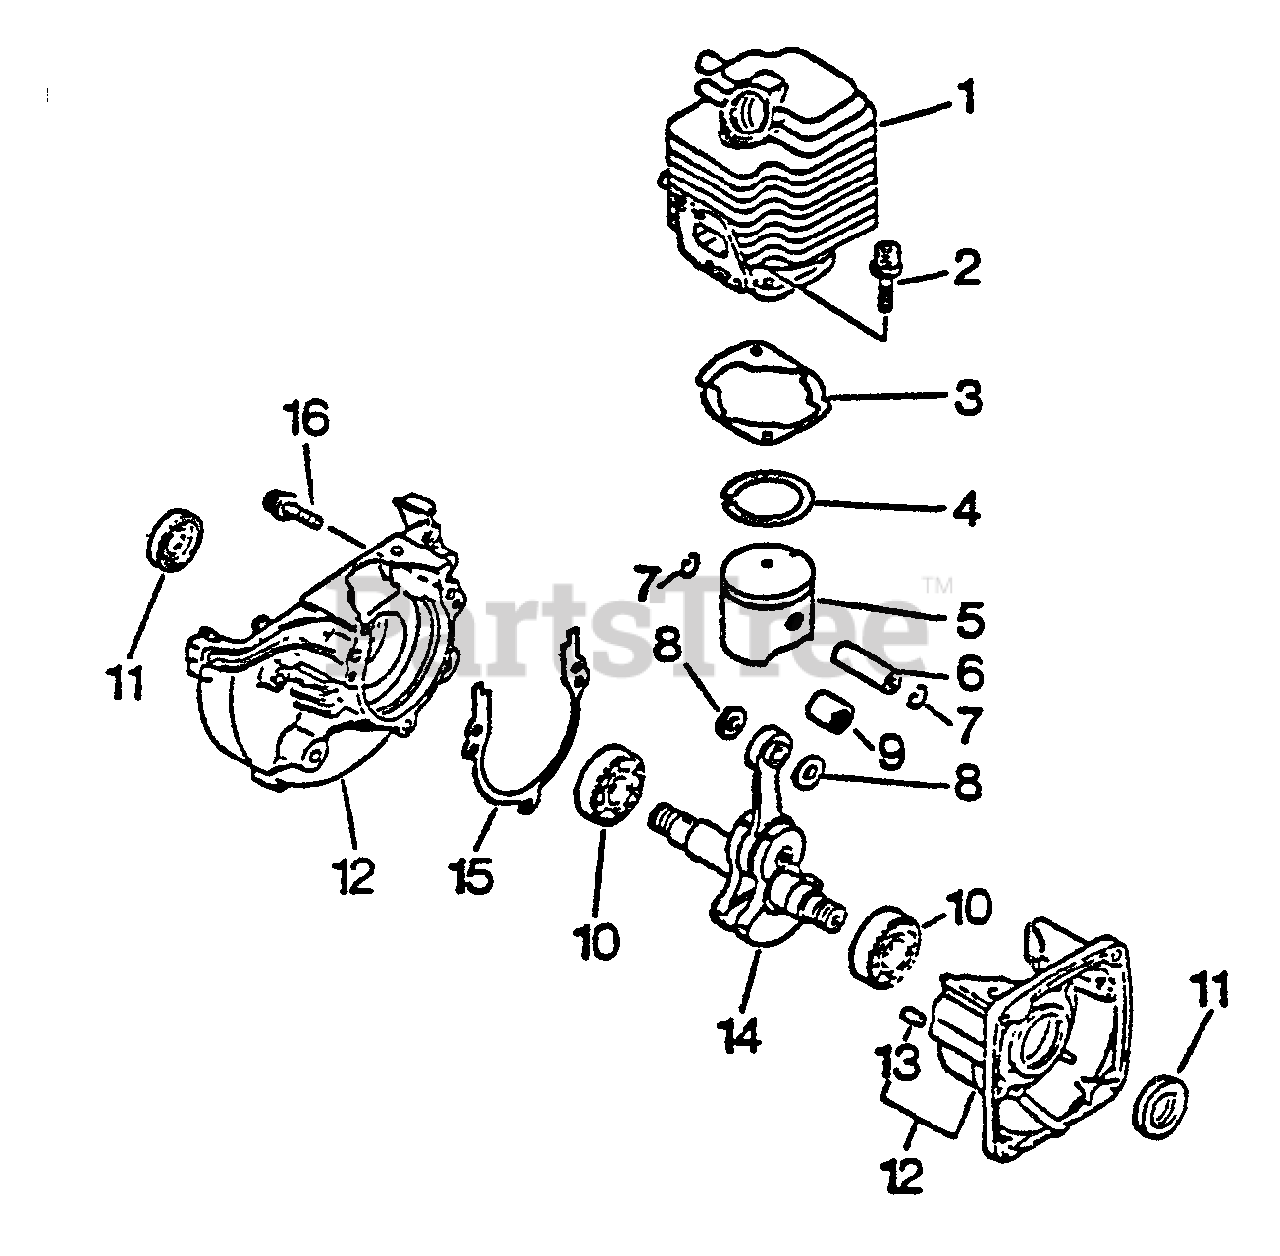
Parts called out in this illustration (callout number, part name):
2	BOLT 5×22
3	GASKET, CYLINDER
4	RING, PISTON
5	PISTON
6	PIN, PISTON 8
7	RING, SNAP
8	WASHER, THRUST
9	BEARING, NEEDLE
10	BEARING, BALL - 6201 C3
11	SEAL, OIL 12
12	CRANKCASE KIT
13	PIN, LOCATING 4
14	CRANKSHAFT ASSY
15	GASKET, CRANKCASE
16	SCREW 5×28
